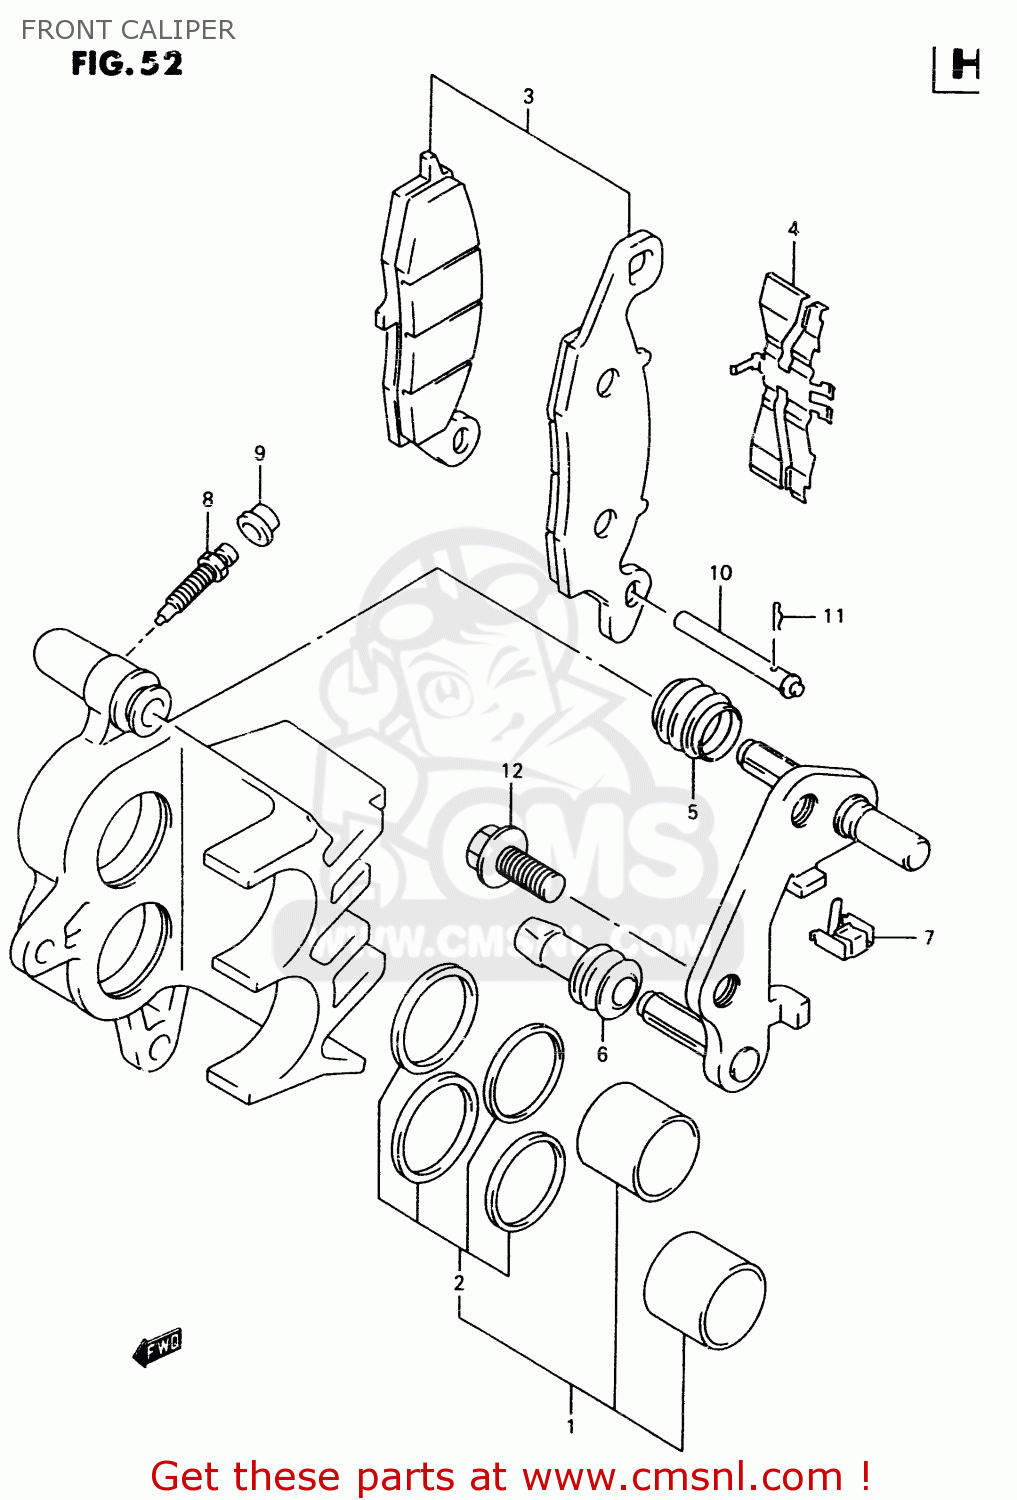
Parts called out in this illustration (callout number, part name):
1	PISTON SET
2	SEAL SET,PISTON
3	PAD SET (NAS)
4	SPRING,PAD,R
5	BOOT,AXLE
6	INSULATOR,AXLE
7	GUIDE,PAD
8	BLEEDER
9	CAP,BLEEDER PLUG
10	PIN,PAD
11	CLIP,PAD PIN
12	BOLT
